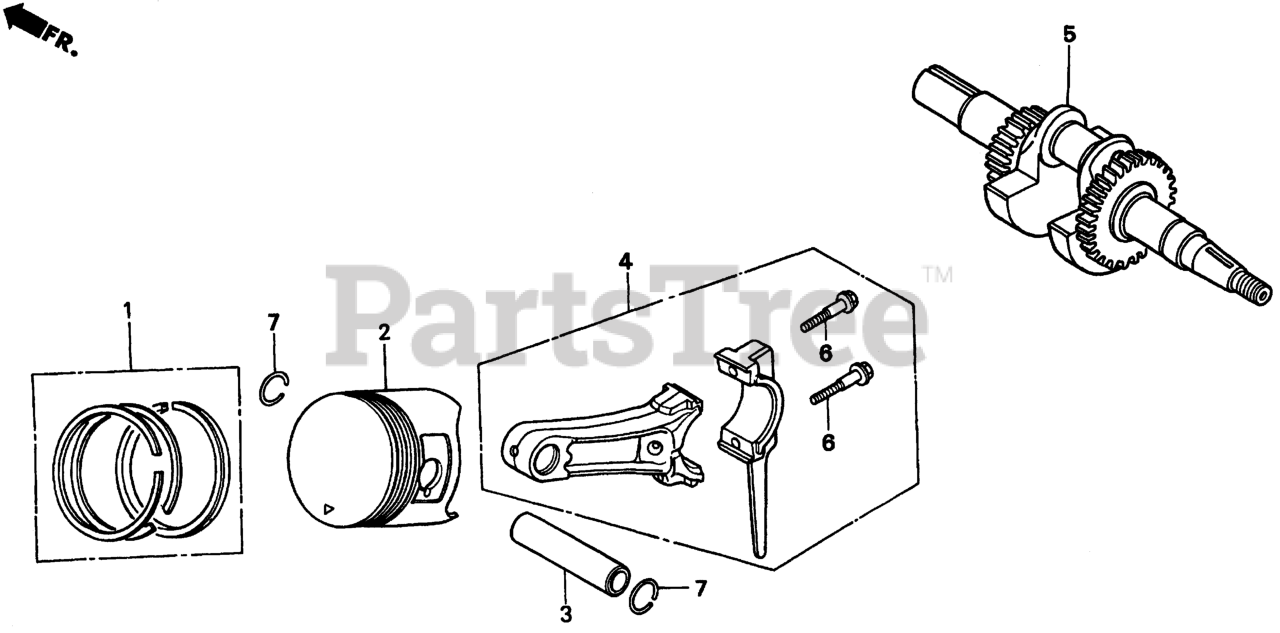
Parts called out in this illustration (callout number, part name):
1	RING SET, PISTON (STD)
1	RING SET, PISTON (OS 0.25) (NIPPON) Use up to Engine SN 2120317.
1	RING SET, PISTON (OS 0.25) (TEIKOKU) Use up to Engine SN 2120317.
1	RING SET, PISTON (OS 0.50) (NIPPON) Use up to Engine SN 2120317.
1	RING SET, PISTON (OS 0.50) (TEIKOKU) Use up to Engine SN 2120317.
1	RING SET, PISTON (OS 0.75) (NIPPON) Use up to Engine SN 2120317.
1	RING SET, PISTON (OS 0.75) (TEIKOKU) Use up to Engine SN 2120317.
1	RING SET, PISTON (OS 0.25)
1	RING SET, PISTON (OS 0.50) Use from Engine SN 2582392.
1	RING SET, PISTON (OS 0.50) (TEIKOKU)
1	RING SET, PISTON (0.75) (NIPPON) (NA USE ALT:13013-ZE1-014)
1	RING SET, PISTON (0.75) (TEIKOKU)
2	PISTON (STD)
2	PISTON (0.25)
2	PISTON (OS 0.25) Use up to Engine SN 2582392.
2	PISTON (0.50)
2	PISTON (OS 0.50)
2	PISTON (0.75) Use up to Engine SN 2120317.
2	PISTON (0.75)
3	PIN, PISTON
4	ROD ASSY., CONNECTING (0.25 LOWER SIZE) (NOT AVAILABLE)
4	ROD ASSY., CONNECTING
5	CRANKSHAFT
6	BOLT, CONNECTING ROD
7	CLIP, PISTON PIN (18MM)
